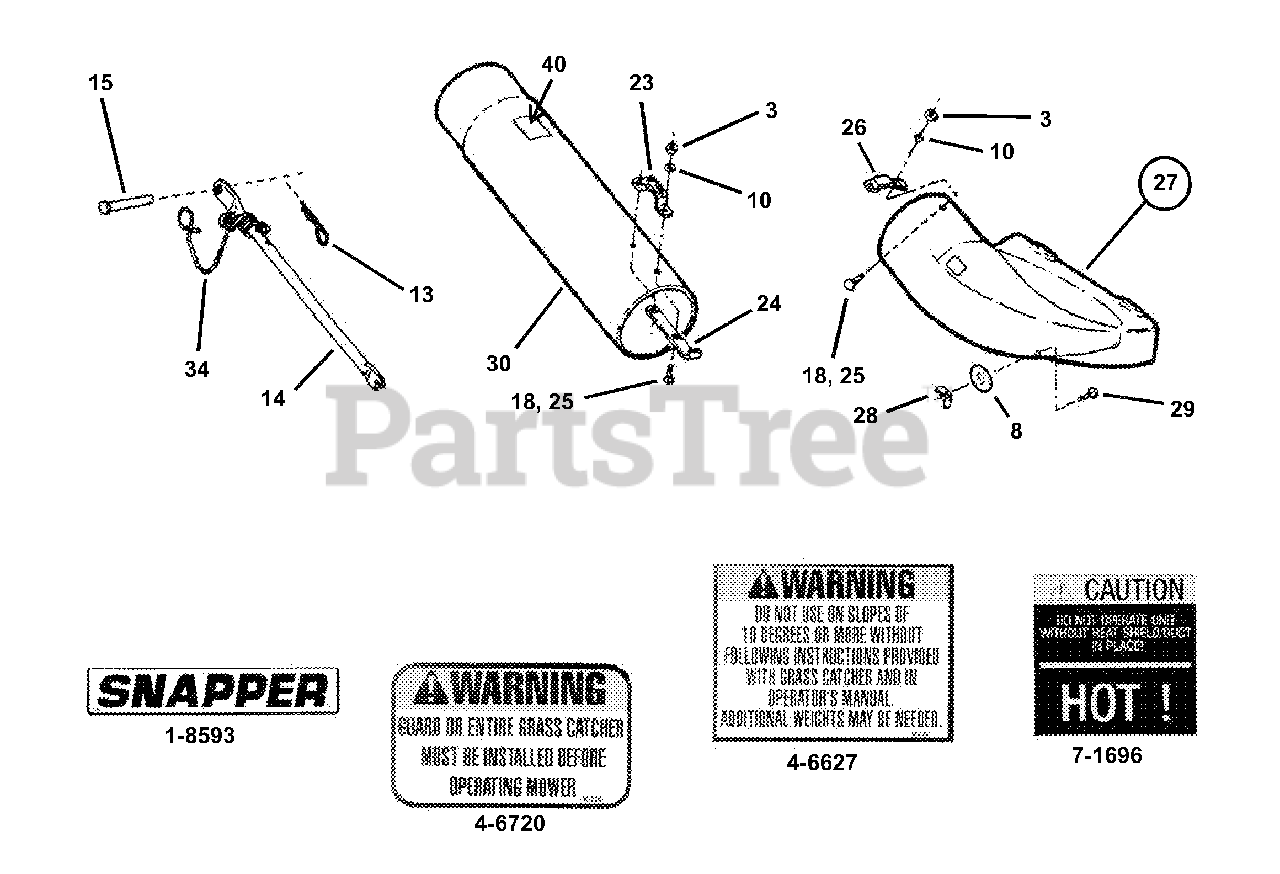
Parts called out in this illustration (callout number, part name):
1-8593	DECAL, SNAPPER
3	NUT, 1/4-20 Hex
4-6627	DECAL, GRASS BAG WARNING
4-6720	DECAL, CHUTE DEFLECTOR
7-1696	DECAL, HEAT SHIELD
8	WASHER, 11/32" Flat
10	WASHER, 1/4" Lock
13	PIN, 3/32 x 1-1/2" Hair
14	BRACE, Rear
15	PIN, 5/16 x 1-11/16" Clevis
18	BOLT, 1/4-20 x 3/4" Carriage
23	HANDLE, Tube
24	BASE, Tube Handle
25	SCREW, 1/4-20 x 3/4" Mach.
26	LATCH, Chute Tube
27	ASSY, Bag Adapter, 33"
28	WING LOCKNUT, 5/16-18
29	BOLT, 5/16-18 x 1" Carriage
30	TUBE, Grass (45" long)
34	ASS'Y, Spring & Hook
40	DECAL, Warning
